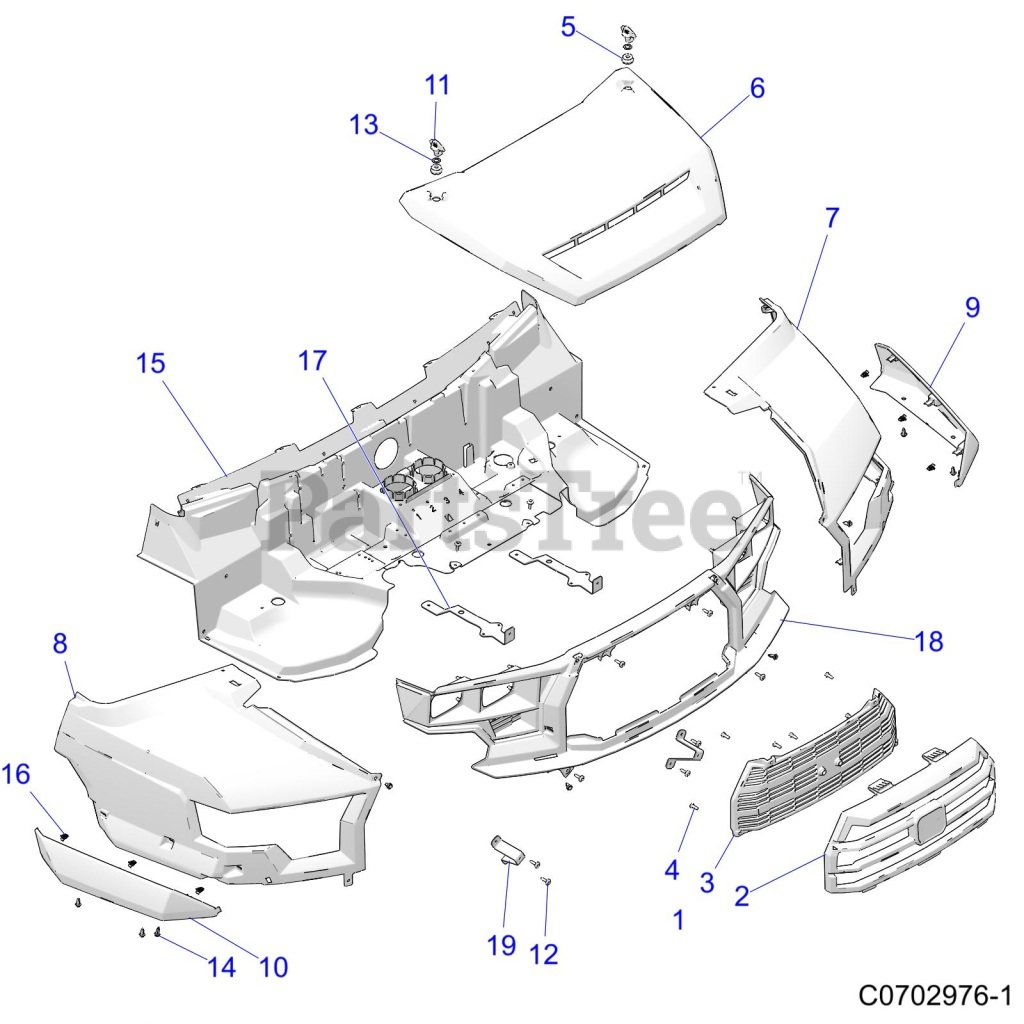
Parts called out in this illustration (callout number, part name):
1	ASM., GRILL, GRAVELY
2	GRILL, FRONT, UPPER, BLACK
3	GRILL, UPPER, TRIM
4	SCR-TXPH-#14 X .75 HI-LO RIE
5	GROMMET-LATCH
6	HOOD-ARNS,I.RED
7	FENDER-FRONT,ARNS,LH,I.RED
8	FENDER-FRONT,ARNS,RH,I.RED
9	FLARE-FENDER,ARNS,LH,BLK
10	FLARE-FENDER,ARNS,RH,BLK
11	LATCH, 1/4 TURN
12	SCR-TXTH-M6X1.0X25 RIE
14	RIVET-TUFLOK,.315-.325X.787 (5
15	LINER-HOOD,BLK
16	CLIP, DASH TRIM METAL
17	BRKT-MOUNT,RADIATOR,ARNS,BLK
18	BEZEL-HEADLIGHT
19	BRKT-FASCIA MOUNT
